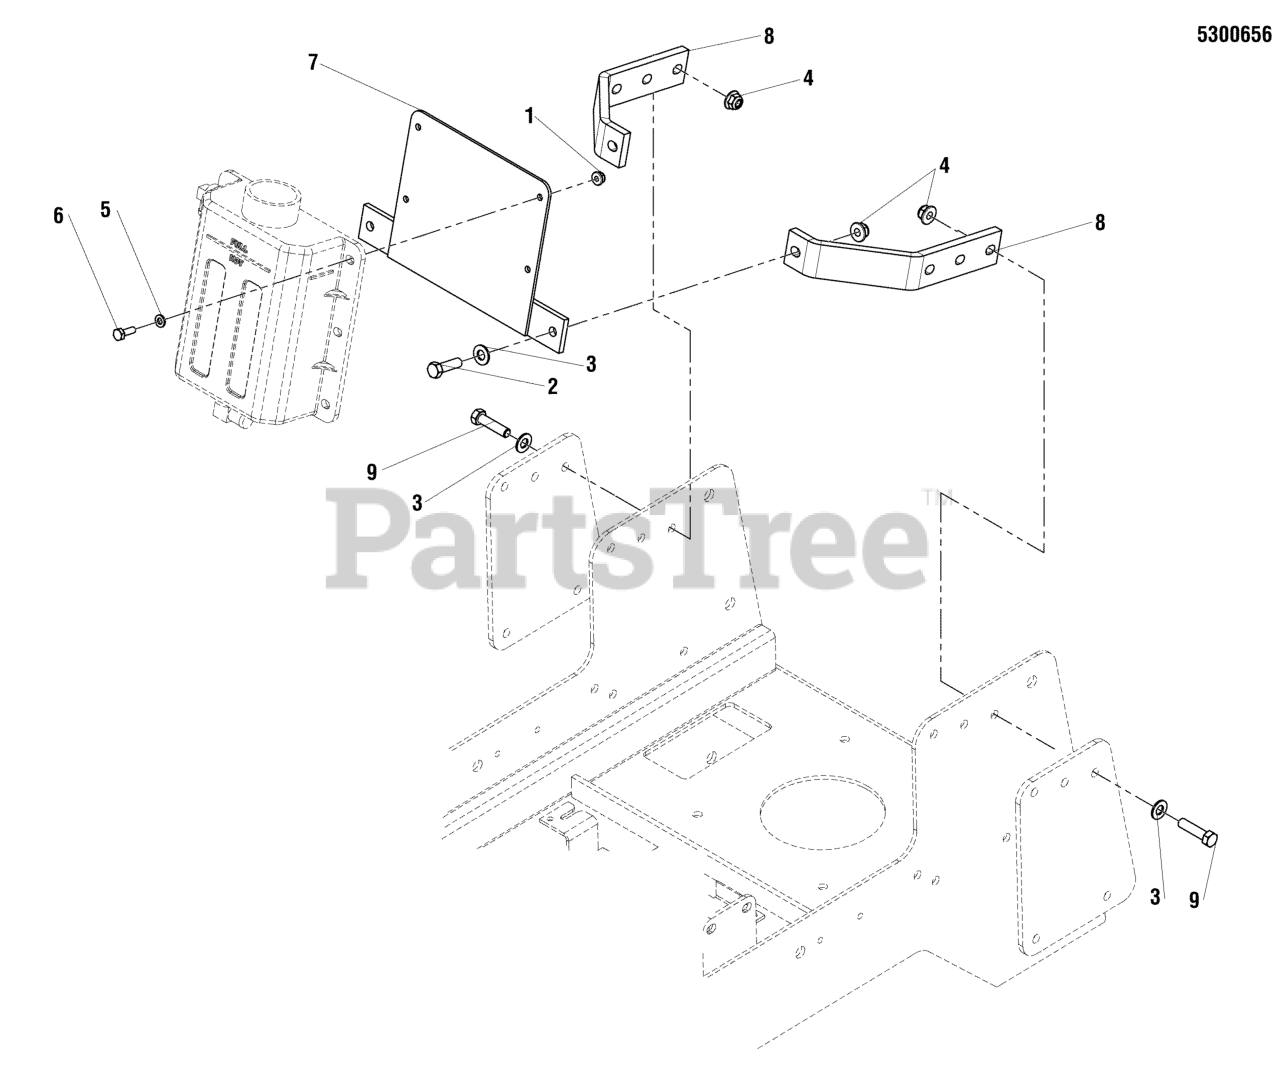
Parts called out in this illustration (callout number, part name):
1	NUT, 1/4-20 HEX NYLOCK FLANGE
2	BOLT, 3/8-16 X 1-1/4" GD5 CZ
3	WASHER, 3/8 SAE
4	NUT, 3/8-16 HEX NYLOCK FLANGE
5	BOLT, 1/4-20 X 3/4" GD5 YZ
6	WASHER, 1/4 SAE
7	WELD, HYD TANK MOUNT
8	BRACKET, HYDRAULIC TANK
9	BOLT, 3/8-16 X 1-1/2" GD5 CZ
